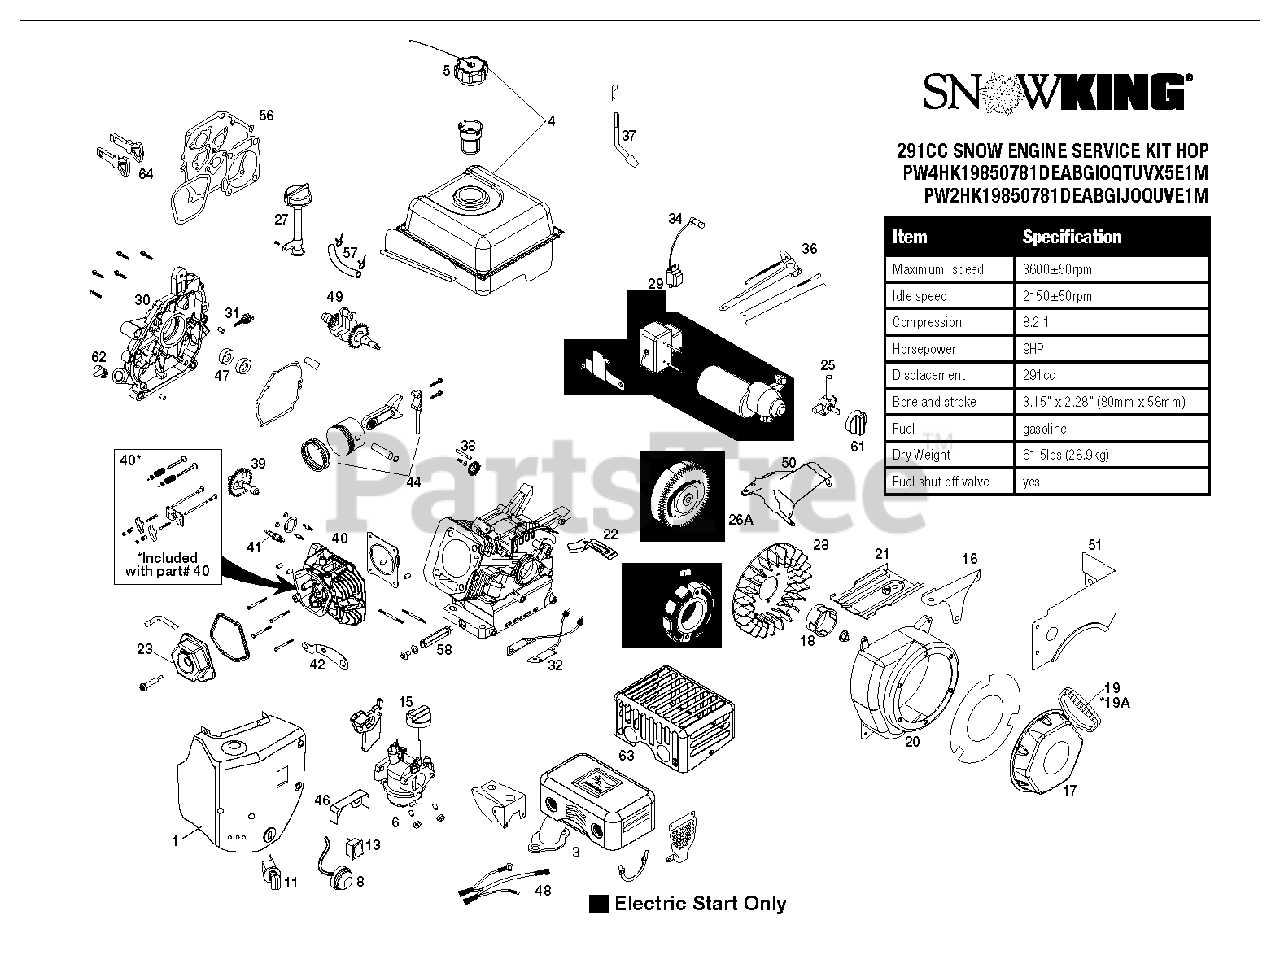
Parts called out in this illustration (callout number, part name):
1	HEATER.BOX.ASSY.SNOW(SKSN2100)
3	MUFFLER.ASSY.SNOW(SKSN4200)
4	FUEL TANK ASSY - SNOW (291CC)
5	FUEL.TANK.CAP.SNOW(SKSN4301)
6	CARBURETOR.ASSY.SNOW(SKSN2302)
8	PRIMER.BULB.ASSY(SKSN4304)
10	ELECTRIC.START.ASSY(SKSN2400.2
10A	STARTER, ELECTRIC, 230V
11	KEY.SWITCH.ASSY.SNOW(SKSN4401)
13	ON/OFF.SWITCH.SNOW(SKSN4403)
15	CHOKE.KNOW.SNOW(SKSN4500)
16	GOVERNOR.LINK.SHIELD(SKSN2501)
17	RECOIL.START.ASSY.(SKSN2600)
18	STARTER.CUP.SMALLSNOW(SKSN2601
19	STARTER.GRIP.SNOW(SKSN2603.1)
19A	HANDLE.RECOIL.DELUXE.LCT
20	HOUSING.BLOWER.ASM
21	SHIELD.CYLINDER.SNOW(SK4141010
22	SHIELD.U/FYWHL.CHARG(SKSN4604)
23	VALVE.COVER.LCT.414CC.
25	FUEL.PETCOCK.SNOW(SKSN4900)
26	FLYWHL.ASSY.ELECT.(SK2911701)
26A	FLYWHL.ASSY.MANUL.(SK2911700)
26B	FLYWHEEL.EL.ST.SKSNO2401.1
27	HIGHOIL.FILL.ASSY.KIT(SKSN4911
28	FLYWHEEL.FAN
29	IGNITION.COIL.(CDI).291-414CC
29A	COIL.IGN.CDI.SKSN2403.1
30	CRANKCASE.COVER.ASY(SK2913600)
31	DIPSTK.OIL.BLK.LCTSK4143711.1
32	CHARGING.COIL.AC/DC(SK4141710)
32A	COIL.IGN.CDI.SKSN2403.1
33	ELECTRIC.START.BRKT(SKSN4405)
34	SPARK.PLUG.BOOT.SNW,SKSN4691.1
36	GOVERNOR.ARM.ASSY.(SKSN2502)
37	GOVERNOR.SHAFT.(SK2913100)
38	GOVERNOR.GEAR.ASSY(SK2912900)
39	CAMSHAFT.LCT.291CC
40	CYLINDER.HEAD.ASSY(SK2911000)
41	SPARK.PLUG(SK2911550)
42	CDI.BOX.BRKT.SNOW(SKSN4402)
44	PISTON.AND.ROD.ASSY(SK2911400)
46	SHIELD.VAPOR(SKSN4606)
47	RP KIT.SEAL.LCT.SK2913905
48	WIRE.HARNESS(SKSN4406)
49	CRANKSHAFT.LCT.291CC.SNOW
50	TOP.SHIELD.LCT.
51	FUEL.TANK.SKIRT(SKSN2101)
52	ROCKER ARM KIT
53	PUSH ROD TAPPET KIT
54	CYLINDER.ASSEM.291CC.LCT.SNOW
56	ENGINE.GASKET.KIT(SK2914300)
57	FUEL HOSE KIT
58	EXTENDED OIL DRAIN TUBE
61	FUEL KNOB-SNOW
62	NONREMVABLE.OIL.PLUG(SK4143715
63	SHIELD.MUFFLER.
64	KEY.SET
